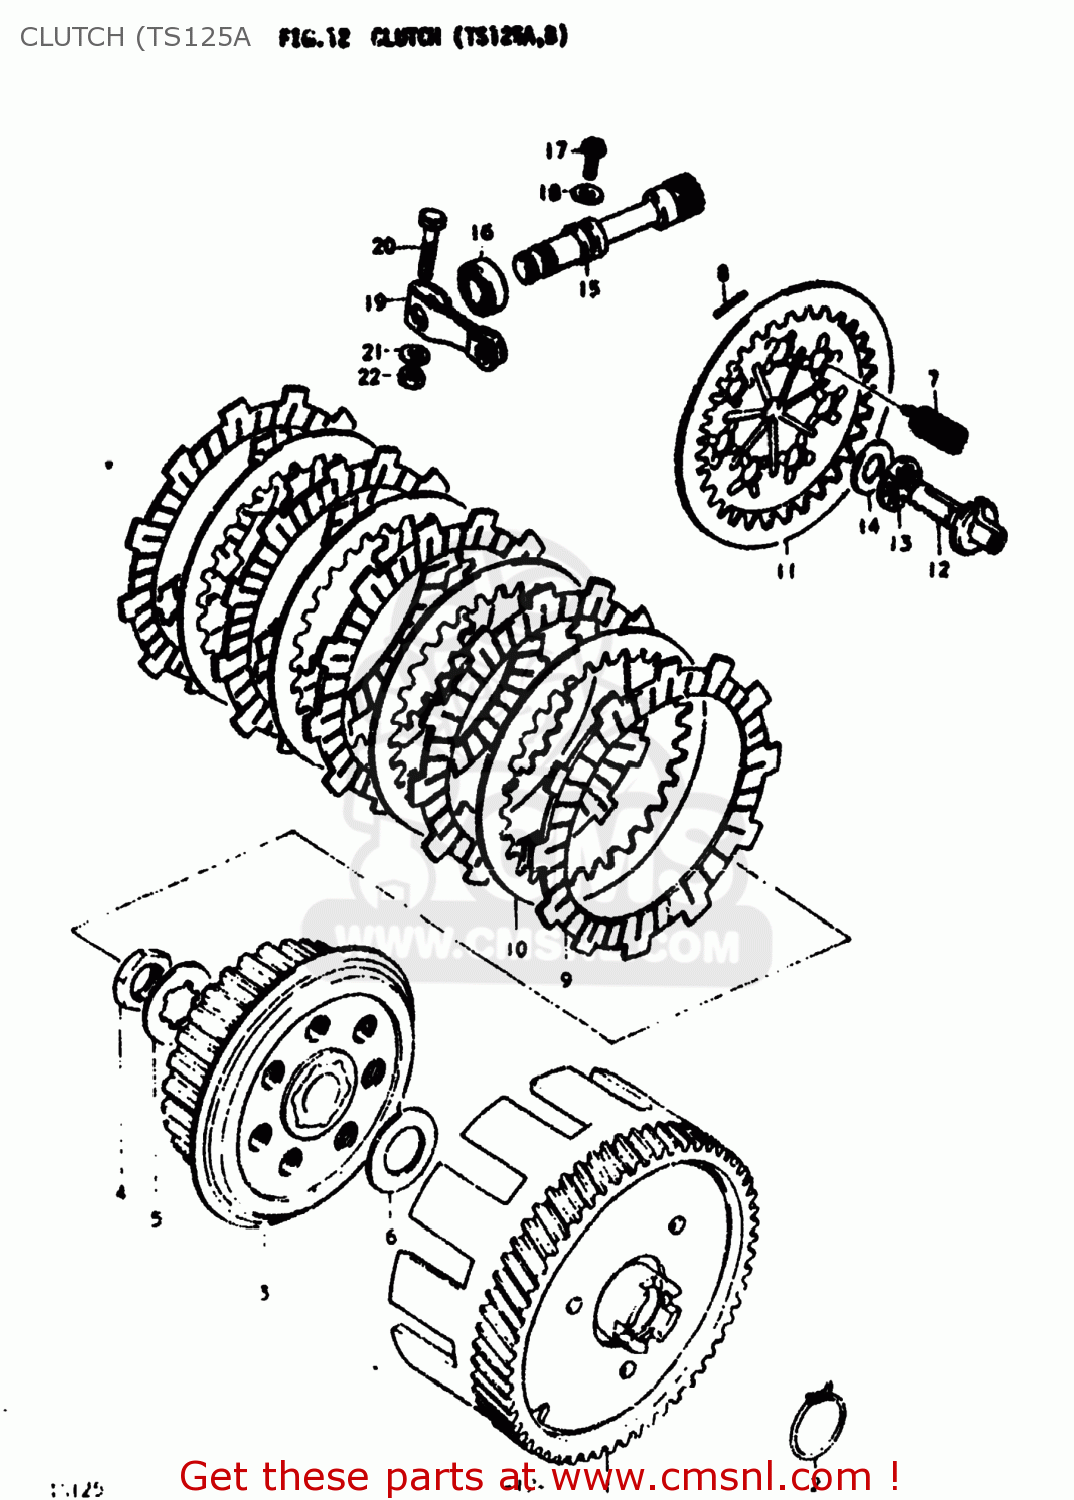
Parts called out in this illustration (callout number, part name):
1	GEAR ASSEMBLY,PRIMARY DRIVE
2	SPRING
3	HUB,CLUTCH SLEEVE
4	NUT
5	WASHER,LOCK
6	WASHER
7	SPRING
8	PIN(2.5X19.8)
9	PLATE,CLUTCH DRIVE
10	PLATE,CLUTCH DRIVEN (NAS)
11	PLATE,CLUTCH PRESSURE
12	RACK,CLUTCH RELEASE
13	BEARING(10X22X2.8)
14	WASHER(10.1X21.4X0.8)
15	PINION,CLUTCH RELEASE
16	OIL SEAL
17	BOLT(6X12)
18	WASHER
19	ARM,CLUTCH RELEASE
20	BOLT
21	WASHER
22	NUT
